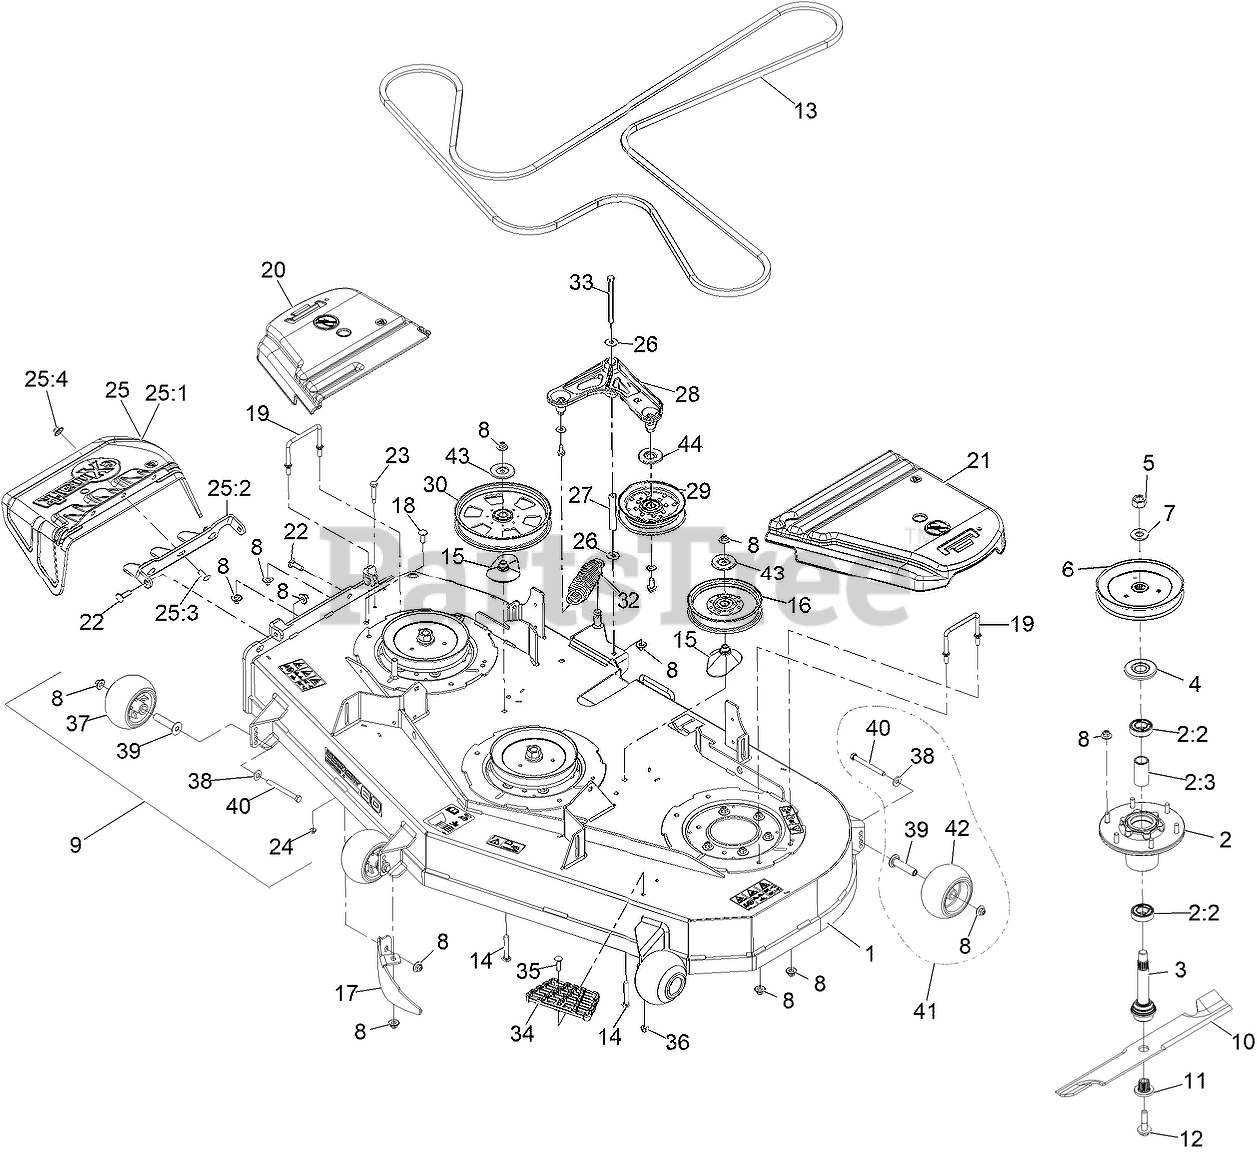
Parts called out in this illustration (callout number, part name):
1	ASM-Deck W/Decals 604
2	ASM-CUTTER HSG WITH BEARINGS
2:2	BEARING-BALL
2:3	SPACER-BEARING
3	ASM-SPINDLE AND SEAL
4	GUARD,BEARING TOP .989
5	NUT-HEX
6	SHEAVE,BLADE DRIVE 7.25
8	Nut-Nyloc 3/8-16 Flg
9	KIT, ANTI-SCALP ROLLER
10	Blade-Extreme 2, 20.50"
11	BUSHING,SPLINED
12	SCREW,SEMS 1/2-20 X 2.19
13	BELT-V
14	SCREW-CARR
15	SPACER-PULLEY
16	IDLER-PULLEY, FLAT 6.00X1.00
17	DOGLEG - LZ60
18	SCREW-CARR
19	WIREFORM-COVER
20	COVER-BELT, RH
21	COVER-BELT, LH
22	BOLT-CARR
23	BOLT-SHOULDER
25	ASM,DISCHARGE CHUTE
25:1	CHUTE,DISCHARGE
25:2	BRACKET,DISCHARGE CHUTE
25:3	SCREW-CARR
25:4	Nut-Nyloc 3/8-16 Flg
27	BUSHING
28	IDLER ARM ASM
29	IDLER-PULLEY, FLAT
30	PULLEY-IDLER, FLAT
32	SPRING-EXTENSION
33	SCREW-HH
34	STEP-DECK
35	Bolt-Carriage 5/16-18 X 1 1/4
36	NUT-HF, NI
37	ROLLER-SCALP, ANTI
38	WASHER-BELLEVILLE
39	AXLE, ROLLER
40	SCREW-HH 3/8-16 X 3 3/4 GR 8
41	KIT-ANTISCALP ROLLER
42	ROLLER-SCALP, ANTI
43	SHIELD-DUST
44	SHIELD-GUARD, DUST
